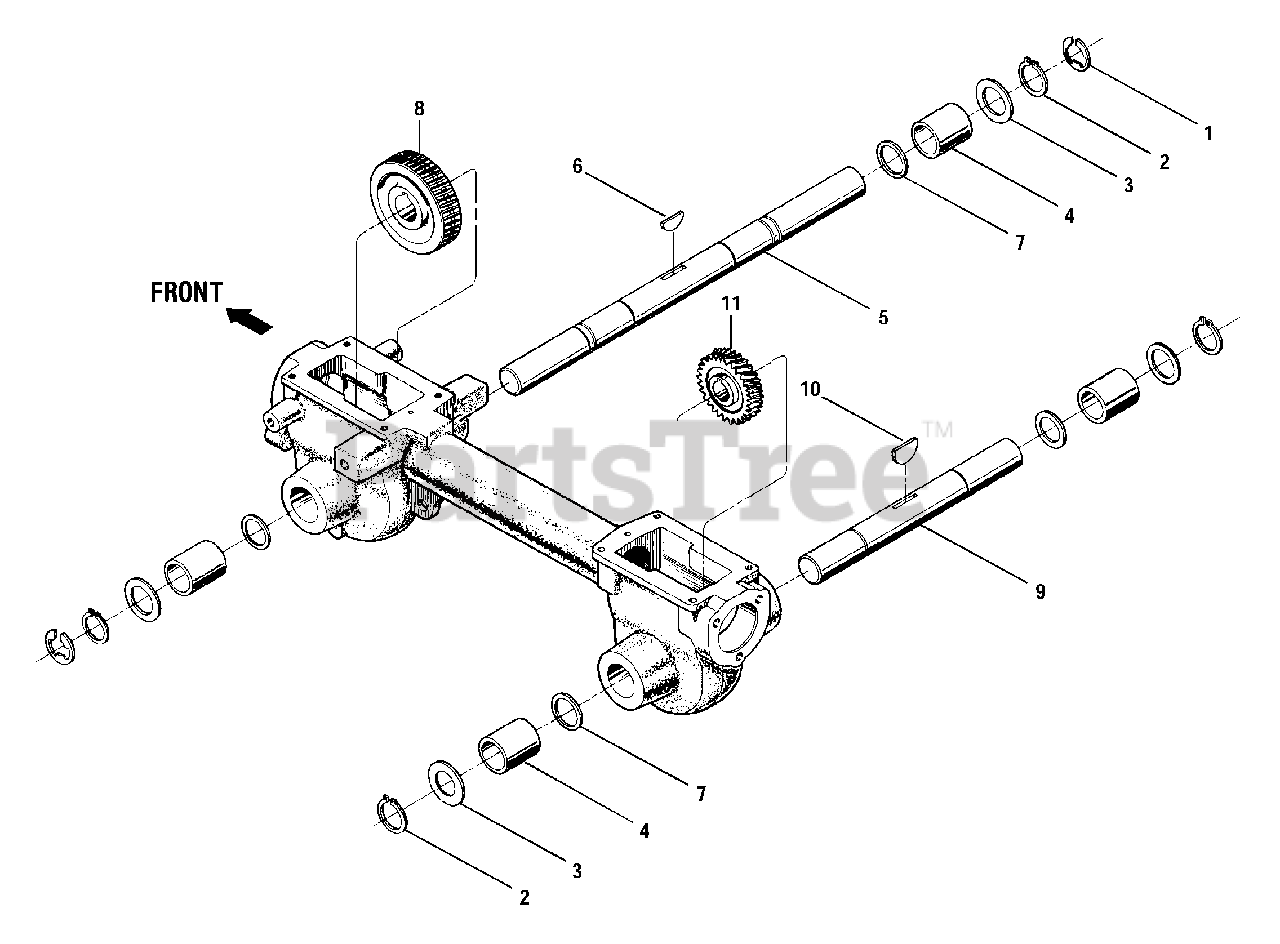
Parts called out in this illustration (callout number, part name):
1	Retainer, Snap Ring, "E" Type
2	Retainer, Snap Ring
3	Shim, 0.062" thick
4	Bronze Bushing
5	Wheel Shaft
6	Key, Hi-Pro, 1/4 x 1
7	Spacer
8	Worm Gear, Wheel Shaft
9	Tiller Shaft
10	Woodruff Key
11	Worm Gear, Tiller Shaft
